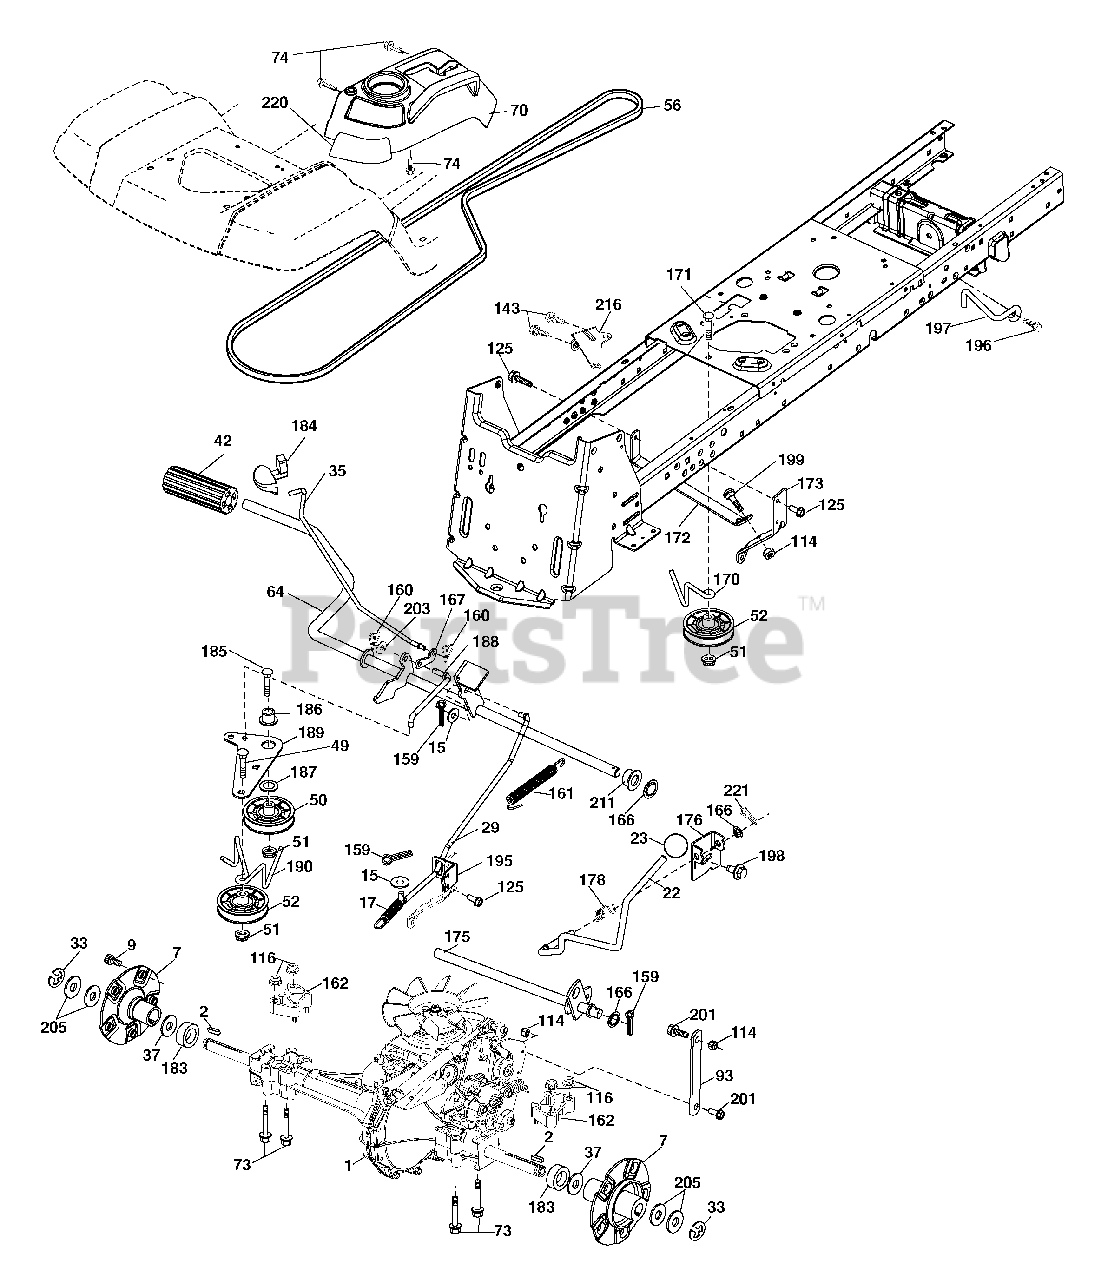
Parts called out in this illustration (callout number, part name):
2	Key 1/4 x 2.5
7	Hub Asm. Wheel
9	Bolt Hub Wheel
15	Washer 13/32 x 13/16 x 16 Ga.
17	Spring, Brake
22	Shifter Rod
29	Rod, Brake
35	Rod, Brake, Park
42	Cover, Foot Pedal
50	Pulley Idler Flat
51	Lock Nut 3/8-16
52	Idler V-Groove 910" Offset
56	V-Belt, Drive
64	Shaft Asm. Pedal Brake Control
70	Control Asm.
73	Bolt Hex Flghd 5/16-18 x 3.75
74	Screw 1/4 x 1/2
93	Link Shift
114	Nut Lock Hex w/Insert 5/16-18 unc
116	Nut Lock Hex Flange 5/16-18
125	Screw 5/16-18 x 3/4
143	Screw Thdrol 5/16-18 x 1/2
159	Pin Cotter 1/8 x 3/4
160	Retainer Clip
161	Spring, Return, Clutch
162	Spacer Trans.
166	Nut Push .625
167	Latch Brake Parking
170	Keeper Belt Centerspan
171	Bolt
172	Strap Torque LH
173	Strap Torque RH
175	Shaft Asm Shift
176	Arm, Shift Rod
178	Spring Shift
183	Spacer Split
184	Handle Parking Brake
185	Bolt Rdhd Sqnk 3/8-16 x 2-1/2
186	Spacer Retainer
187	Washer
188	Link Clutch Ground Drive
189	Bellcrank Ground Drive
190	Keeper Bellcrank Ground Dr.
195	Bracket Rod Brake
196	Screw 3/8-16 x 1
197	Bracket Clutch Anti-Rotation
198	Screw 7/16-14 x 7/8 Flghd
199	Bolt Rdhd Sqnk 5/16-18 unc x 1
201	Bolt Shoulder 5/16-18 unc
203	Washer 11/32 x 11/16 x 16 Ga.
216	Bracket Pulley Idler
220	Reflector RH
221	Retainer Spring Clip Handle
